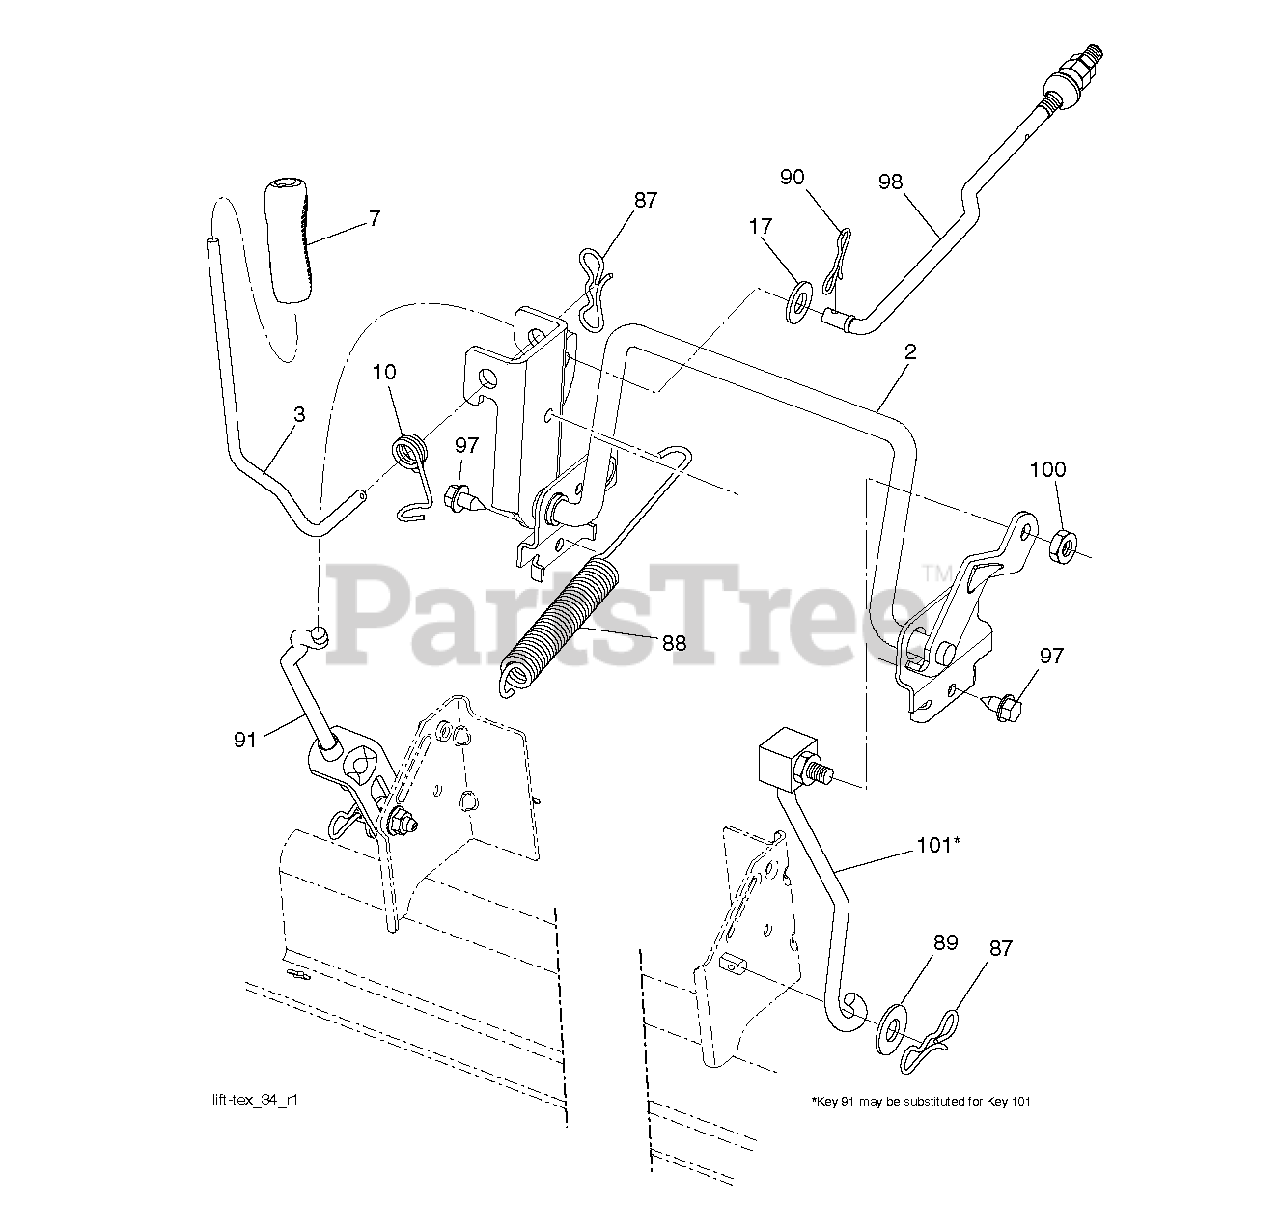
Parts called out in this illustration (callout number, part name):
2	SHAFT LIFT DECK WELD
3	LEVER.LIFT.HANDLE.LT
7	GRIP.HANDLE.LIFT.PVC.BLACK
10	SPRING.TORSION.LIFT.HANDLE
17	WASHER
87	PIN.COTTER.7/16.BOW TI.
88	SPRING SPRING LIFT ASSIST 97
89	WASHER.CLEAR.ZINC
90	PIN.COTTER.5/16.BOW TI
91	LINK.ASM.LIFT.REAR
98	LINK.ASM.SUSP.FRONT.MW
100	LOCKNUT
101	LINK.ASM.LIFT.FIXE.38/42/46"
